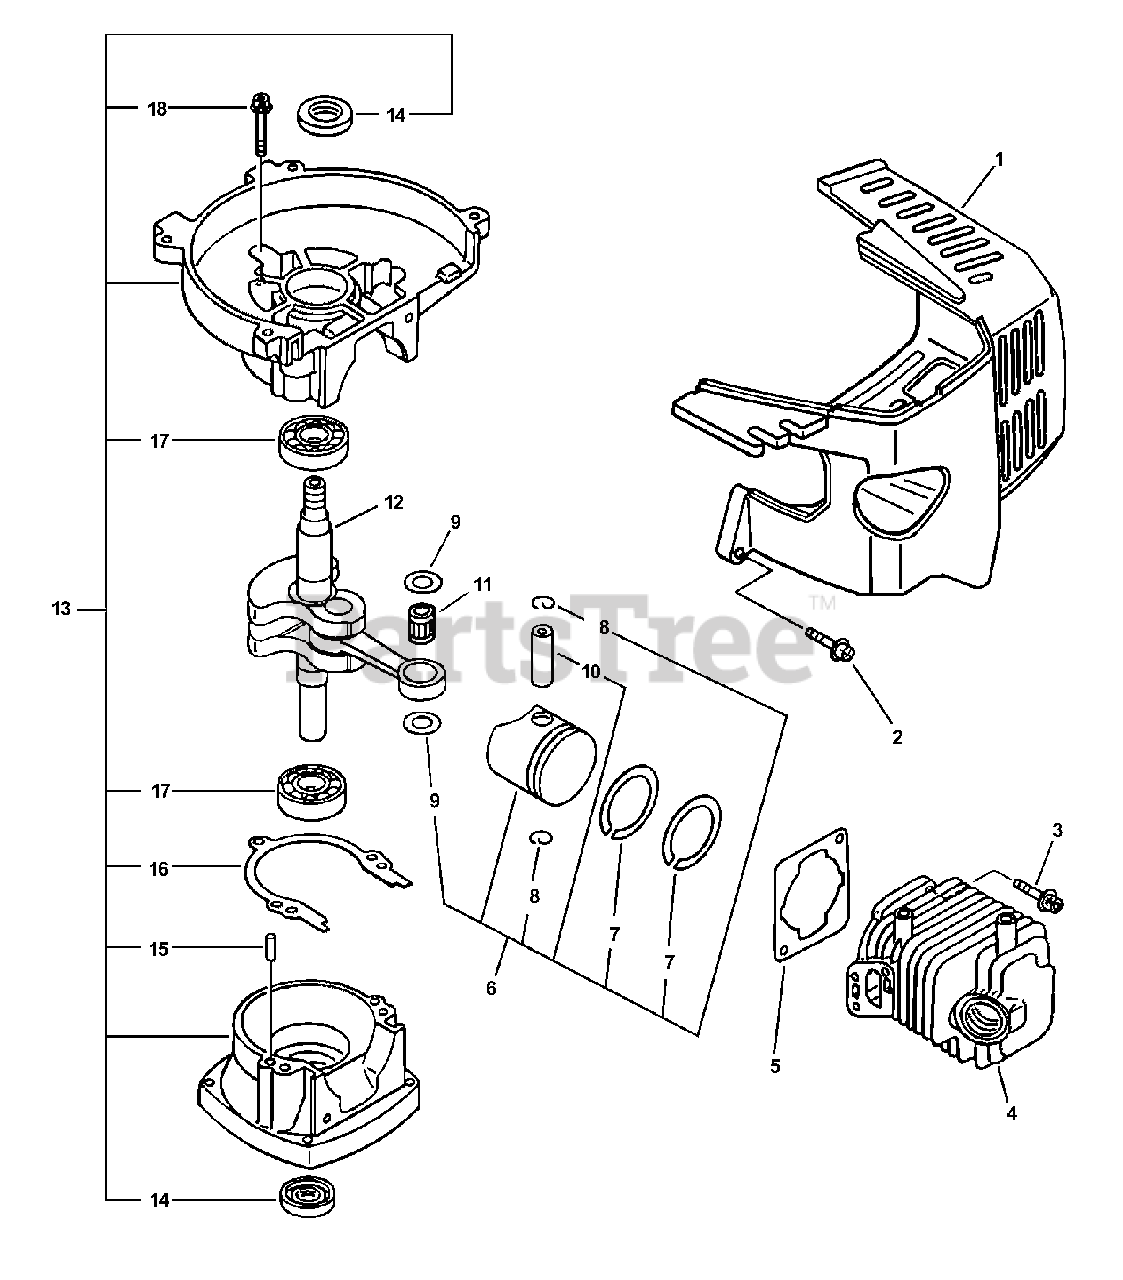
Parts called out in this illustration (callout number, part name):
1	COVER, ENGINE
2	SCREW - 4X22
3	SCREW - 5X22
4	CYLINDER
5	GASKET, CYLINDER
6	PISTON KIT
7	RING, PISTON
8	RING, RETAINING
9	SPACER, PISTON
10	PIN, PISTON
11	BEARING, NEEDLE
11	BEARING, NEEDLE - 8
12	CRANKSHAFT ASSY
13	CRANKCASE KIT
14	SEAL, OIL
15	PIN - LOCATING
16	GASKET, CRANKCASE
17	BEARING, BALL - 6201
18	SCREW - 5X28
